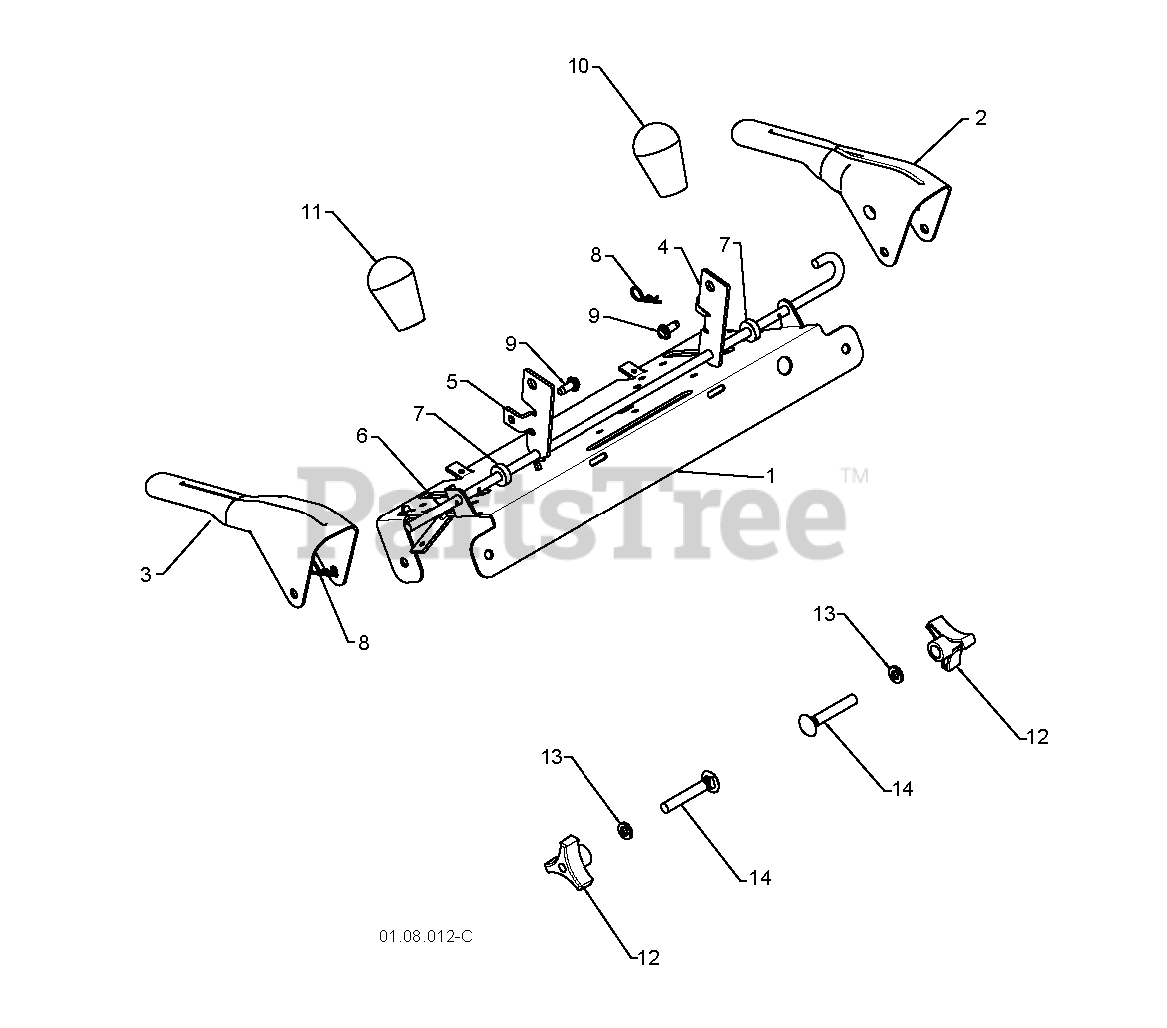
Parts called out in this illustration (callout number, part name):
1	PANEL.CONTROL
2	LEVER.CONTROL.LH.BLACK
3	LEVER.CONTROL.RH.GREY
4	ARM.TRACTION.ROD.YZ
5	ARM.IMPELLER.ROD.SNOW
6	BAIL.CONTROL.INTERLOCK
7	SPACER.CONTROL.LEVER
8	SPRING RETAINER
9	SCREW 14-20 X 5/8
10	KNOB LEVER, BLACK
11	RED KNOB SHIFTER
12	KNOB.HANDLE.3/8.TRI-POINT.BLAC
13	WASHER
14	BOLT 3/8-16 X 2-1/4
